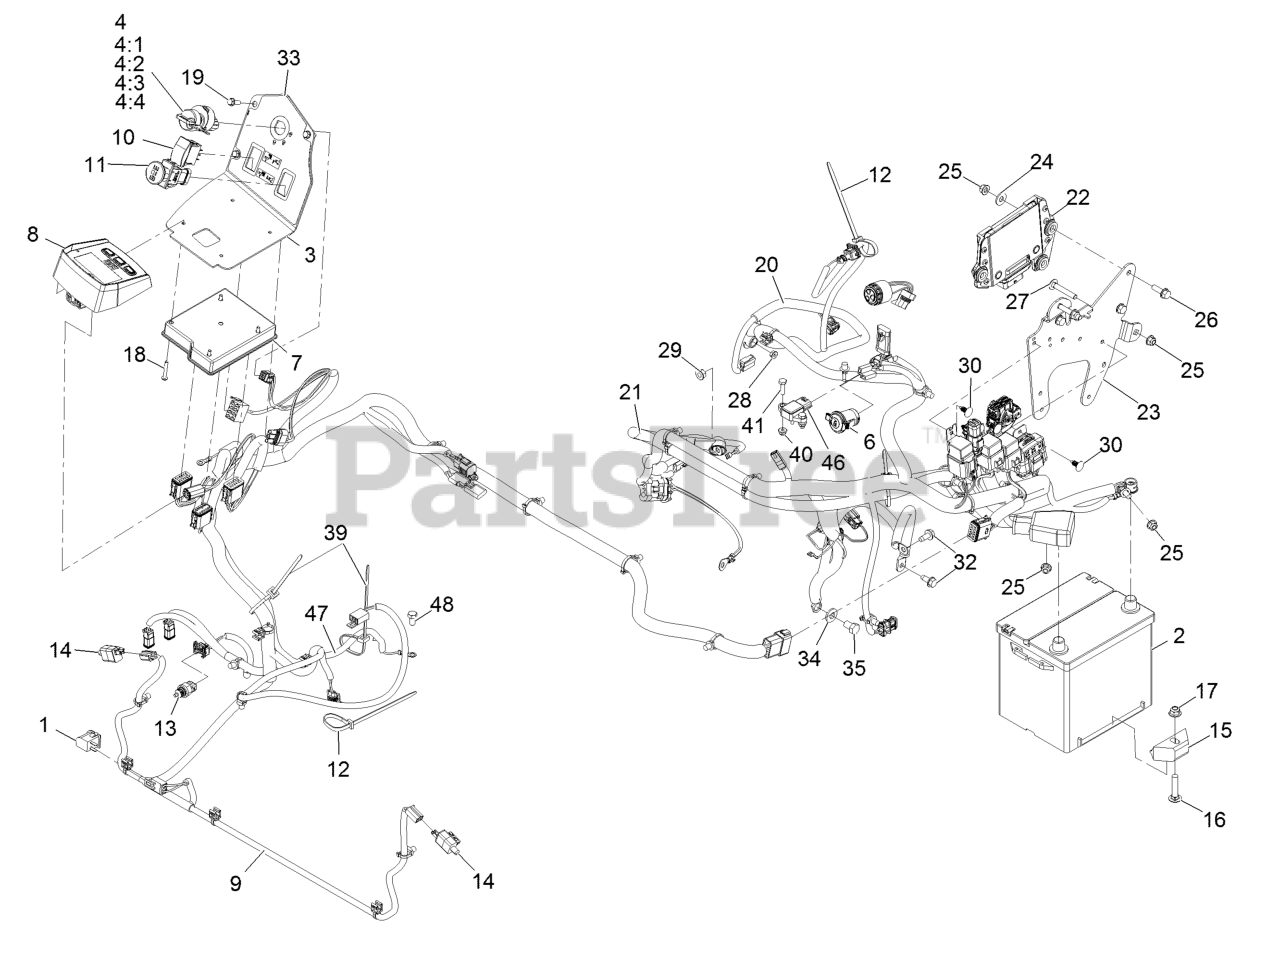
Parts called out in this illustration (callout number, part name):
2	Battery-Dry
3	Plate-Console
4	Ignition Switch ASM
4:1	Switch-Ignition
4:2	Nut-Mounting
4:3	Ignition Key Set
4:4	Washer-Backup
6	Port-Power, 12V
7	Module-Mcu
8	Module, Ldu
9	Harness-Wire
10	Switch, (On)-Off-(On)
11	Switch-PTO, Sealed
12	Tie-Cable 7 15/16 (Large)
13	Sensor-Temperature
15	Retainer-Battery
16	Bolt-Carriage 3/8-16 X 1 3/4
17	Nut-Nyloc 3/8-16 Flg
18	Screw-PPH
19	Screw-Machine 1/4-20 X 3/4
20	Harness-Wire, Yanmar
21	Cable-Battery
22	Ecu ASM
23	Bracket, Ecu Mount [black]
24	Washer-5/16 Std
25	Nut-Nyloc 5/16-18 Flg
26	Screw-HH Flg 5/16-18 X 1
27	Bolt-Carriage 3/16-18 X 2
28	Nut-Hex M6-1 Flg
30	Plug-Plastic
32	Screw-HWH 5/16-18 X 3/4 Tf
33	Decal-Control Panel
34	Washer-Spring Disc 3/8
35	Screw-HH
39	Tie-Cable
40	Nut-Nyloc 1/4-20 Flg
41	Screw-HH 1/4-20 X 7/8
46	Sensor-Atm
47	Harness-Wire, Jumper
48	Bolt
